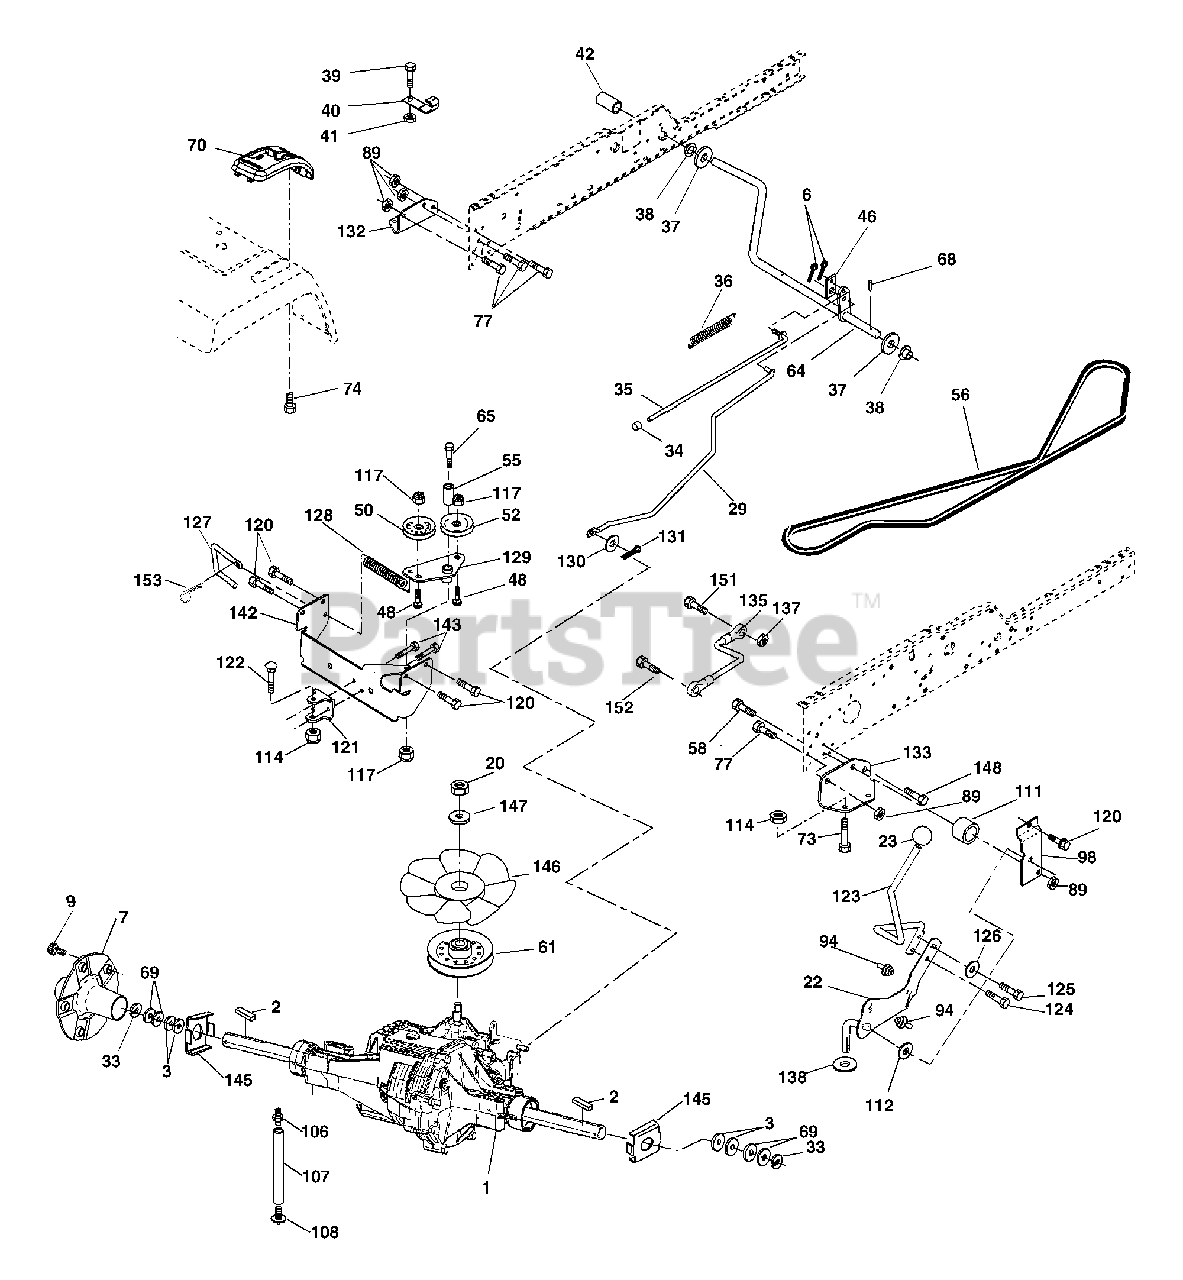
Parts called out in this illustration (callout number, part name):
2	Key Sq. 1/4 x 2.5
3	Washer Thrust
6	Pin, Cotter
7	Wheel, Hub Assembly
9	Bolt, Hub
20	Nut
22	Lever Asm Shift
23	Knob
29	Brake, Rod
33	Ring E
34	Cap, Parking Brake
35	Rod, Parking Brake
36	Spring, Drive Ground
37	Washer 25/32 x 1-1/4 x 16 Ga.
38	Nyliner
39	Screw, Fin. #10-24 x 1
40	Actuator, Interlock Switch
41	Nut Centerlock 10-24 Unc
42	Cover, Pedal
46	Retainer, Spring
48	Bolt Carr. Shoulder 3/8-16 x 1-3/4 Gr. 5
50	Pulley, Idler, Flat
52	Pulley, Idler, Grooved
55	Bearing, Idler
56	V-Belt
58	Bolt Fin Hex 7/16-14 x 1-1/2
61	Pulley, Transaxle
64	Shaft, Brake Pedal
65	Bolt, Shoulder
68	Pin, Roll
69	Washer
70	Console Shift
73	Bolt Hex Flghd 5/16-18 x 3 Gr5
74	Screw Hex Wsh. Hi-Lo 1/4-1/2
77	Bolt Fin Hex 7/16-14 x 1
89	Nut Crownlock 7/16-14 Unc
94	Fastener Christmas Tree
98	Bracket Shift
106	O-Ring Asm Hydro Gear
107	Line Fuel Hydro 15" VGT
108	Cap Asm Vent Hydro Gear
111	Spacer Shift Lever VGTH
112	Washer Nylon High Temp
114	Nut Lock Hex W/Ins 5/16-18 Unc
117	Nut, Lock Flg. 3/8-16
120	Screw 3/8-16 x .75
121	Bracket Strap Torque
122	Bolt 5/16-18 x 2.50
123	Rod Shift
124	Bolt Shoulder 5/16-18 x .561
125	Screw 5/16-18 x 5/8
126	Washer SRRTD 5/16 ID x 1.0 x .125
127	Link Control Clutch
128	Spring Drive GRND
129	Bracket Asm Idler Tensioning
130	Washer 13/32 x 5/8 x 16 Ga.
131	Pin Cotter 3/32 x 3/4
132	Bracket Mtg Hydro 3500 LH VGT
133	Bracket Mtg Hydro 3500 RH VGT
135	Link Asm Control Hydro 3500
137	Nut Lock 5/16-18 NC Thd.
138	Washer Thrust 5/8 x 1.10 x 1/32
142	Strap Torque HG-3500
143	Screw 5/16-18 x 3/4
145	Washer Axle Flange HG-3000
146	Fan 7" Hydro
147	Washer
148	Bolt Hex 7/16-14 x 1-1/4 Gr. 5
151	Bolt Fin Hex 5/16-18 x 7/8
152	Bolt Hex 5/16-18 x 1
153	Spring Retainer
